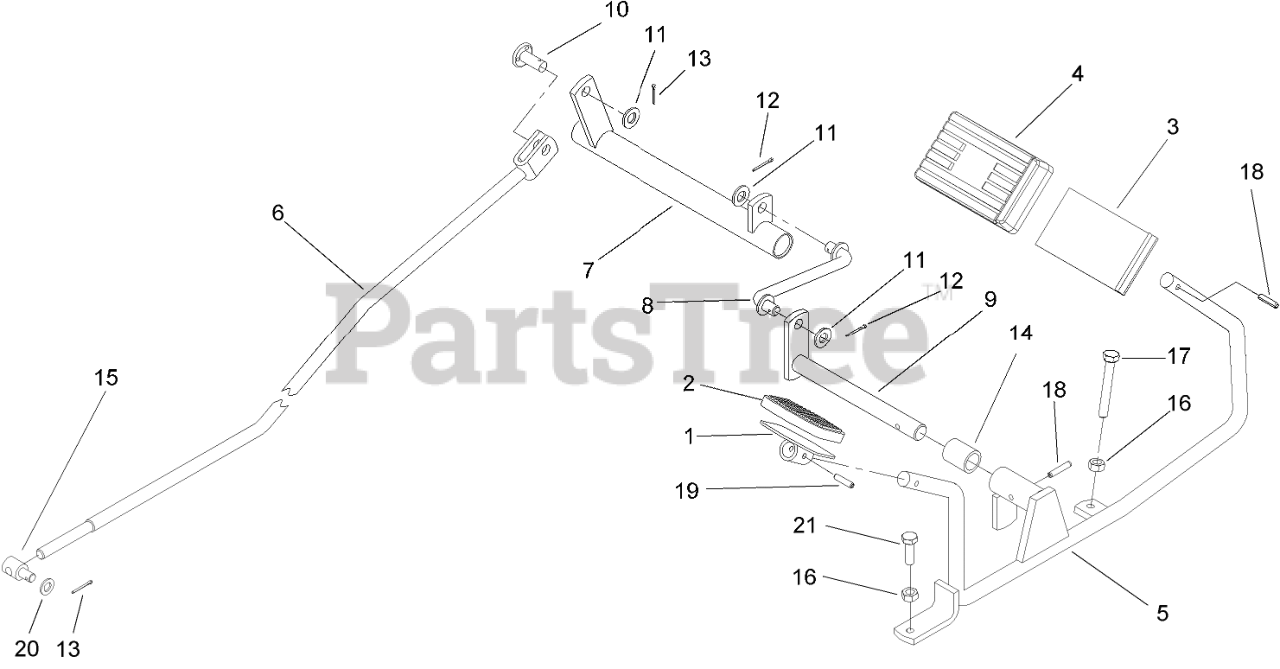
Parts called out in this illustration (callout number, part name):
1	PEDAL-REAR, TRAVEL
2	PAD-PEDAL
3	PEDAL-TRAVEL, FRONT
4	PAD-PEDAL, FRONT
5	ROD-TRAVEL
6	ROD-TIE
7	SHAFT-DIAGONAL
8	LINK-FORMED
9	SHAFT-DIAGONAL
11	WASHER-FLAT
12	PIN-COTTER
13	PIN-COTTER
14	SPACER
16	NUT-HEX
17	SCREW-HH
18	PIN-SPRING
19	PIN-SPRING
20	WASHER
21	SCREW-HH
